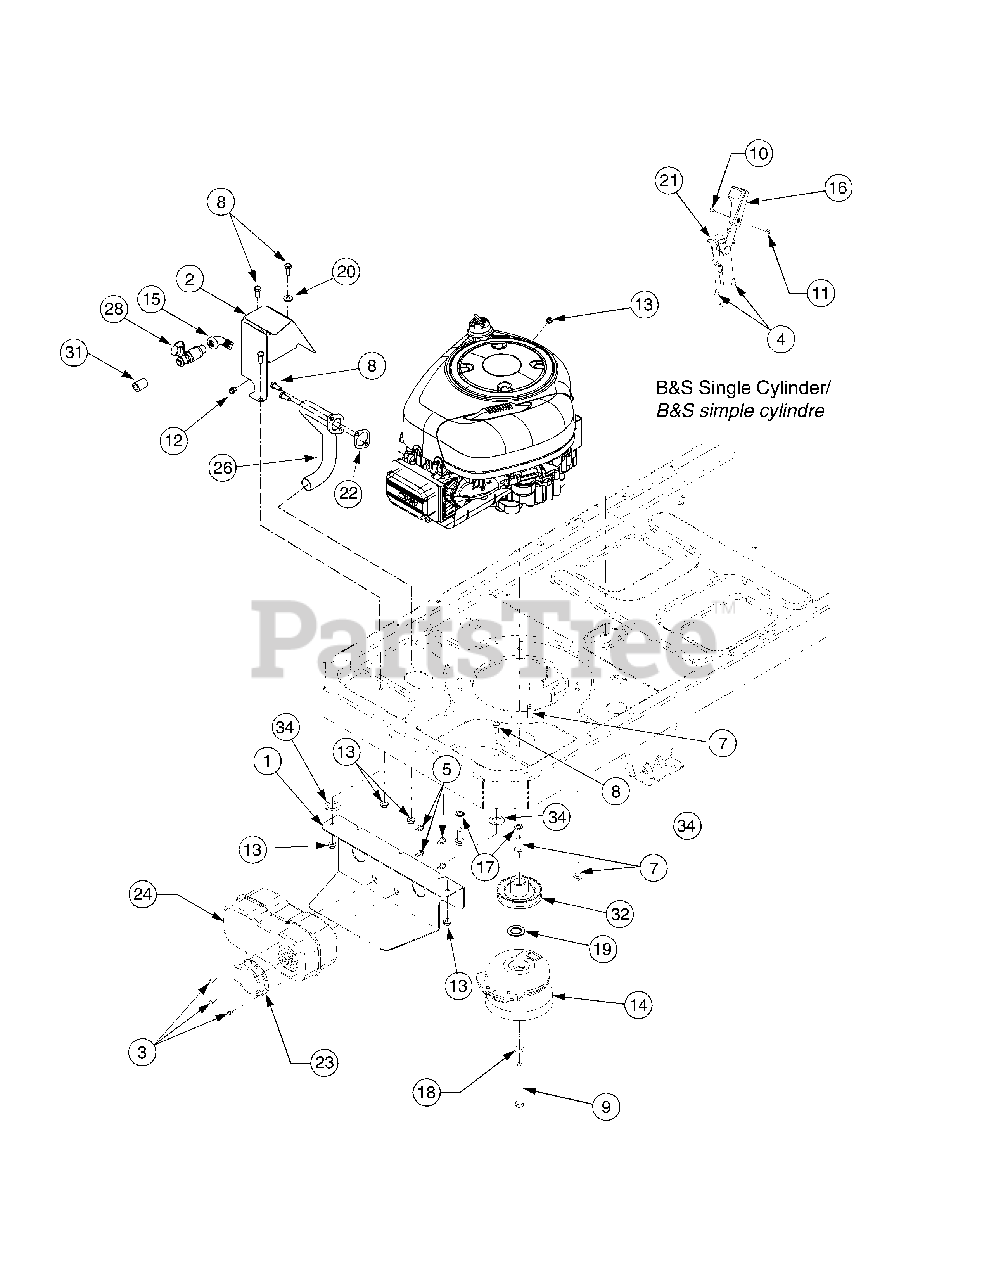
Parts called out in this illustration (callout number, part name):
1	Muffler Mounting Bracket
2	Muffler Tube Heat Shield
3	Hex Wash HD AB S-Tapp Scr #8-.50
4	Hex Wash. Hd. Tapp. Screw #12-16 x .5
5	Hex Wash S-Tapp Scr 1/4-20 x .50
7	TT Screw 3/8-16 x 1.25
8	Hex Bolt 5/16-18 x .75" Lg. Gr. 5
9	Hex Bolt 7/16-20 x 3.25 Gr. 5
10	Torx Screw, #8-32 x .375
11	Hex Nut #8-32, 0.375
12	Sems Hex Nut 1/4-20
13	Flange Locknut 5/16-18 Gr. F, Nylon
14	Clutch Ass’y Electric PTO
15	Elbow Fitting
16	Throttle Control Knob
17	L-Washer 3/8" ID (Ext. Tooth)
18	Lockwasher 7/16 ID
19	Flat Washer 1.03 ID x 1.64 OD x .095
20	Flat Washer .312 ID x .75 OD
21	Throttle Cable 39.0" Lg.
23	Muffler Deflector
24	Muffler
31	Oil Drain Hose
34	Flat Washer .406 ID x 1.5 DE x .105
